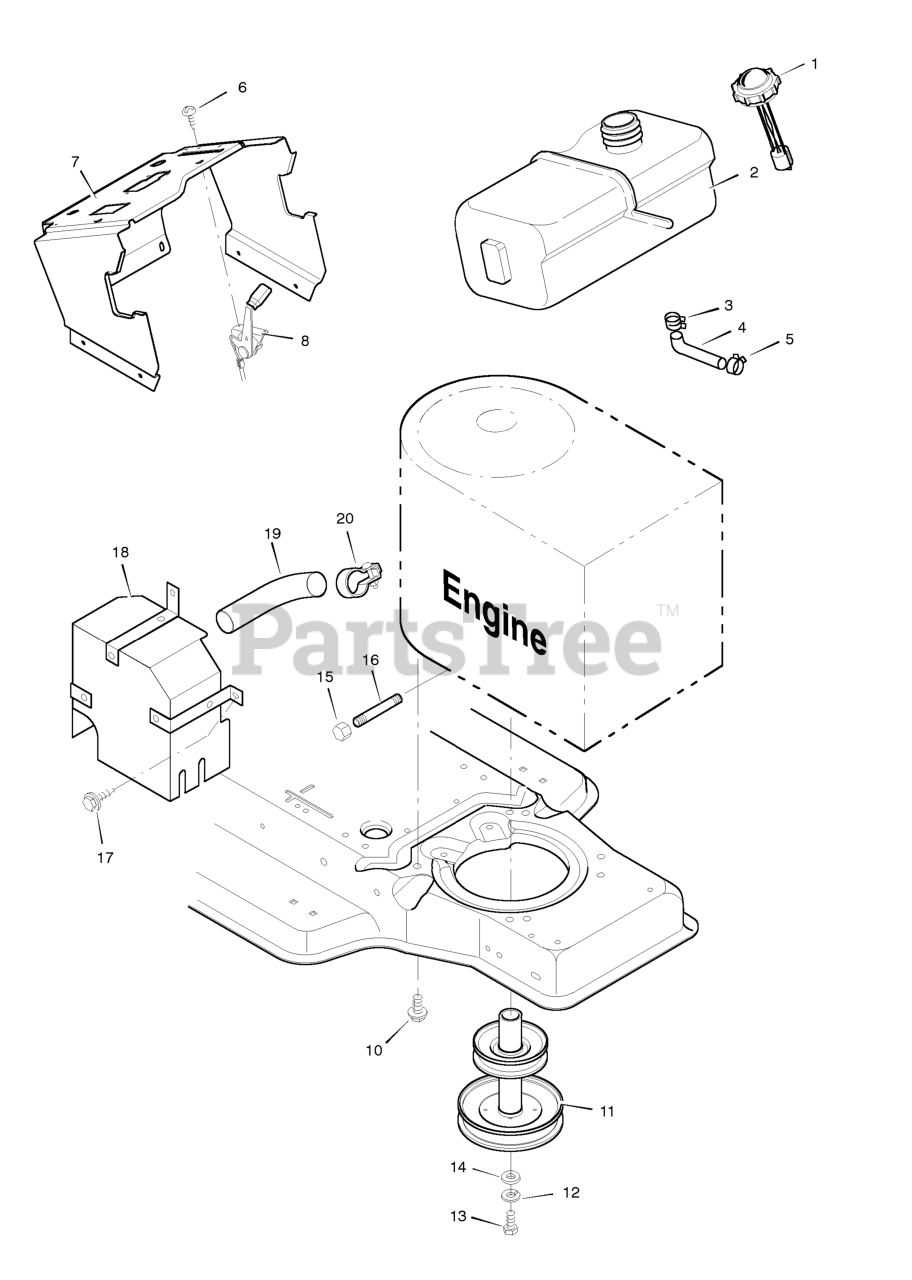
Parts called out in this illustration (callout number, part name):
1	Fuel Cap
2	Fuel Tank
3	Hose Clamp
4	Fuel Line
5	Hose Clamp
7	Support, Dash
8	Throttle Control
9	Engine *
10	Bolt, Engine Mount
11	Stack Pulley Assembly
12	Lockwasher
13	Bolt, Hex
15	Cap, Oil Drain
16	Pipe, Oil Drain
18	Shield, Heat
19	Pipe, Exhaust
